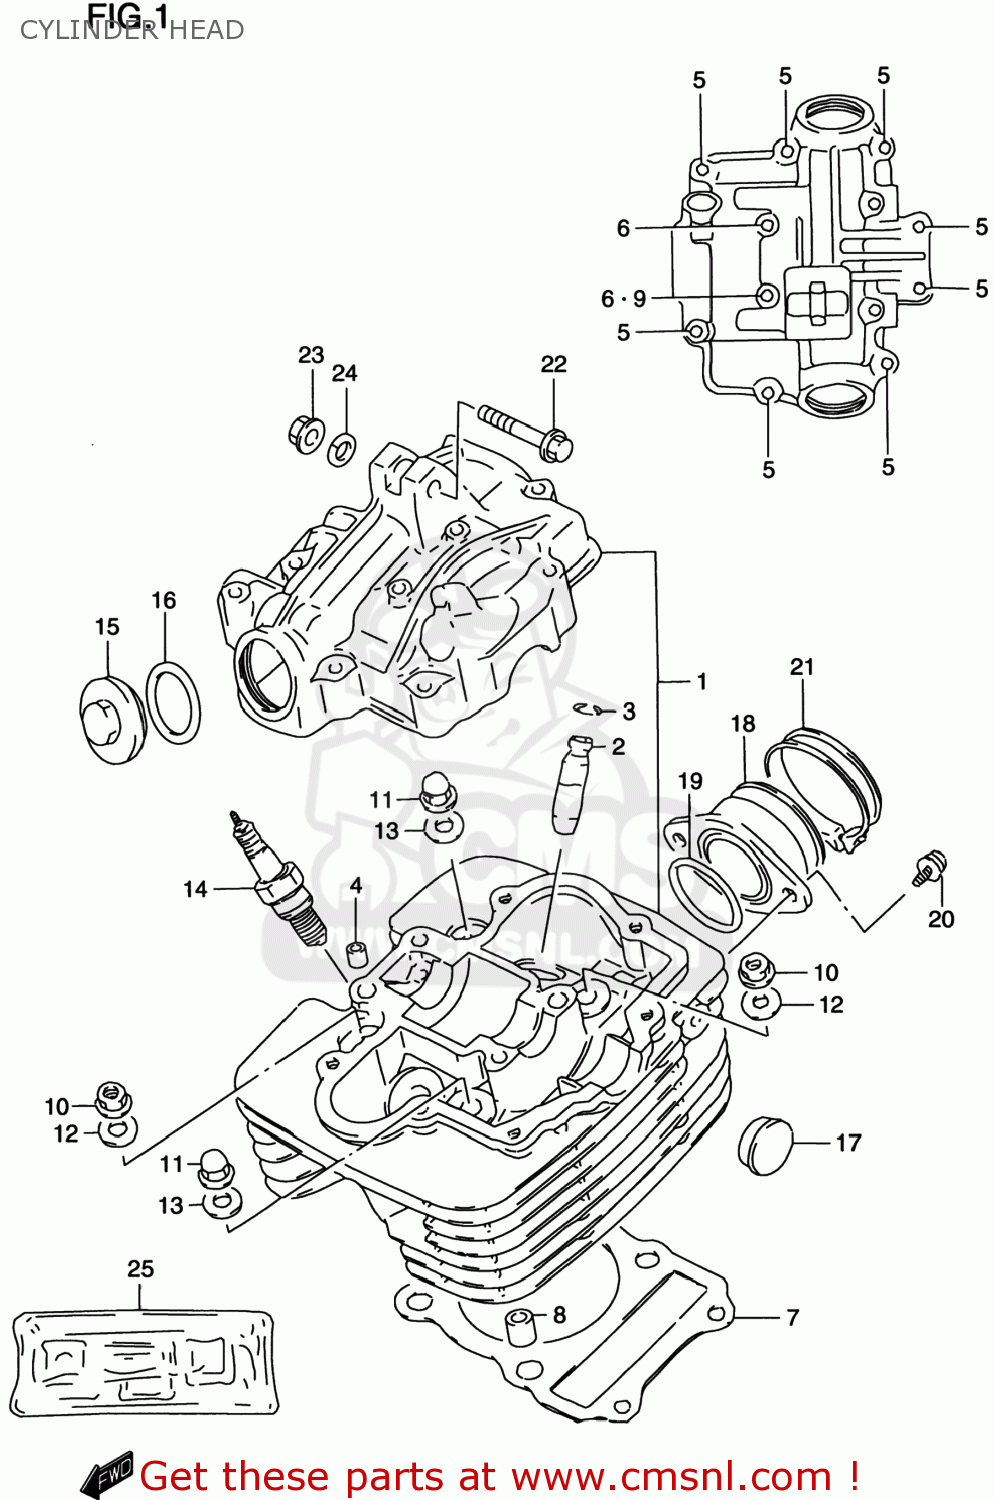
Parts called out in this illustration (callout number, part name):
1	HEAD ASSY,CYLINDER
2	GUIDE,VALVE
3	RING,SNAP
4	PIN(6.2X8X11)
5	BOLT
6	BOLT
7	GASKET,CYLINDER HEAD (NAS)
8	PIN
9	GASKET(5.8X13X1.2) (NAS)
10	NUT
11	NUT
12	WASHER(8.5X19X2.3)
13	GASKET(8.5X17X2.3) (NAS)
14	PLUG,SPARK(DR8EA)
15	CAP,INSPECTION
16	O RING(D:3,ID:29.5)
17	PLUG(OD:22.5)
18	PIPE,INTAKE
19	O RING(D:1.9,ID:34.6)
20	SCREW
21	CLAMP
22	BOLT(8X53)
23	NUT
24	LOCK WASHER
25	GASKET SET (NAS)
